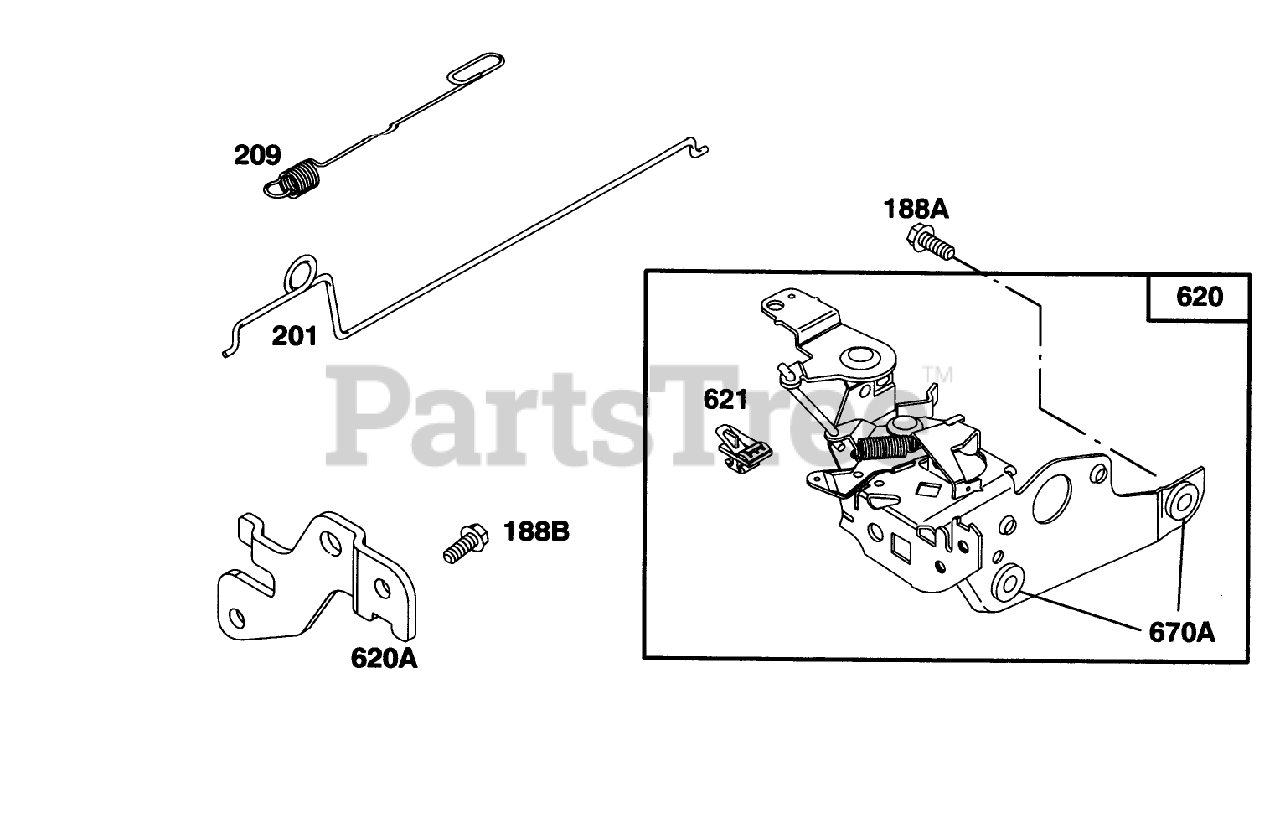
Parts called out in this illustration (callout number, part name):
188A	Screw-Hex.
188B	Screw-Hex.
201	Link-Govemor
209	Spring-Govemor
620	Bracket-Carburetor
621	Switch
670A	Spacer
